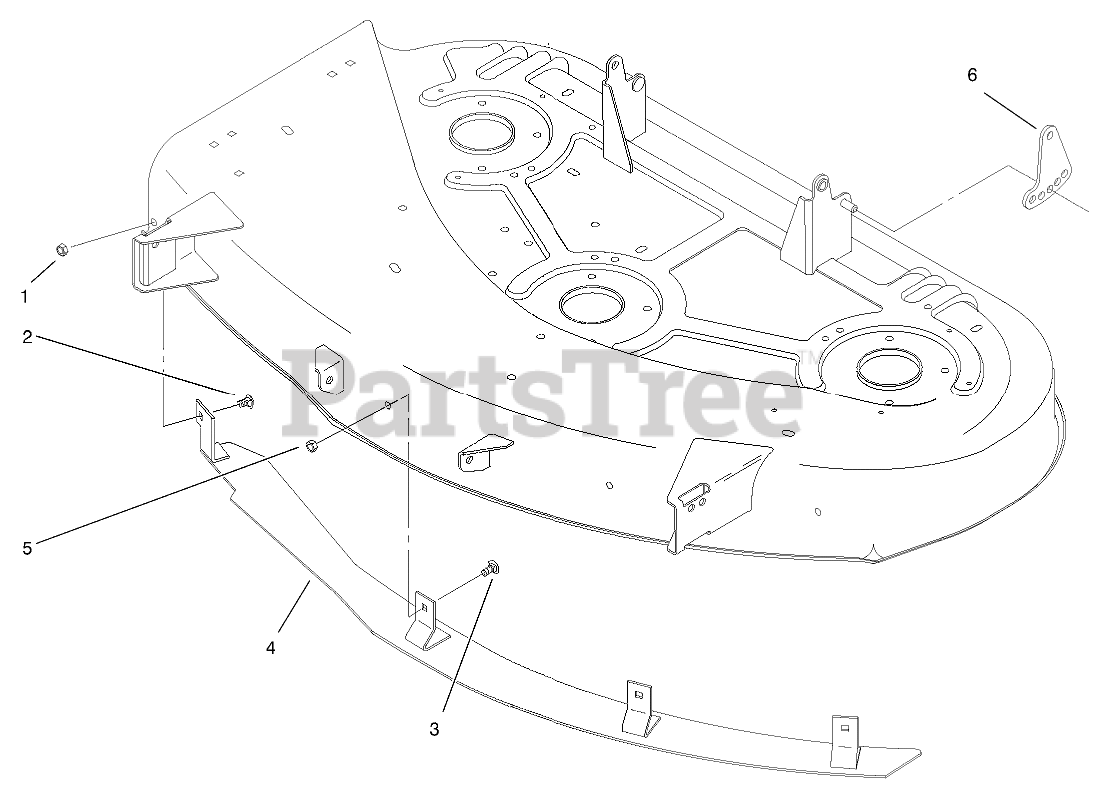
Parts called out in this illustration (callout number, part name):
1	NUT-LOCK, NI
2	SCREW-CARR
3	SCREW-CARR
5	NUT-LOCK, NI
6	LINK-ADJUSTING, HOC
